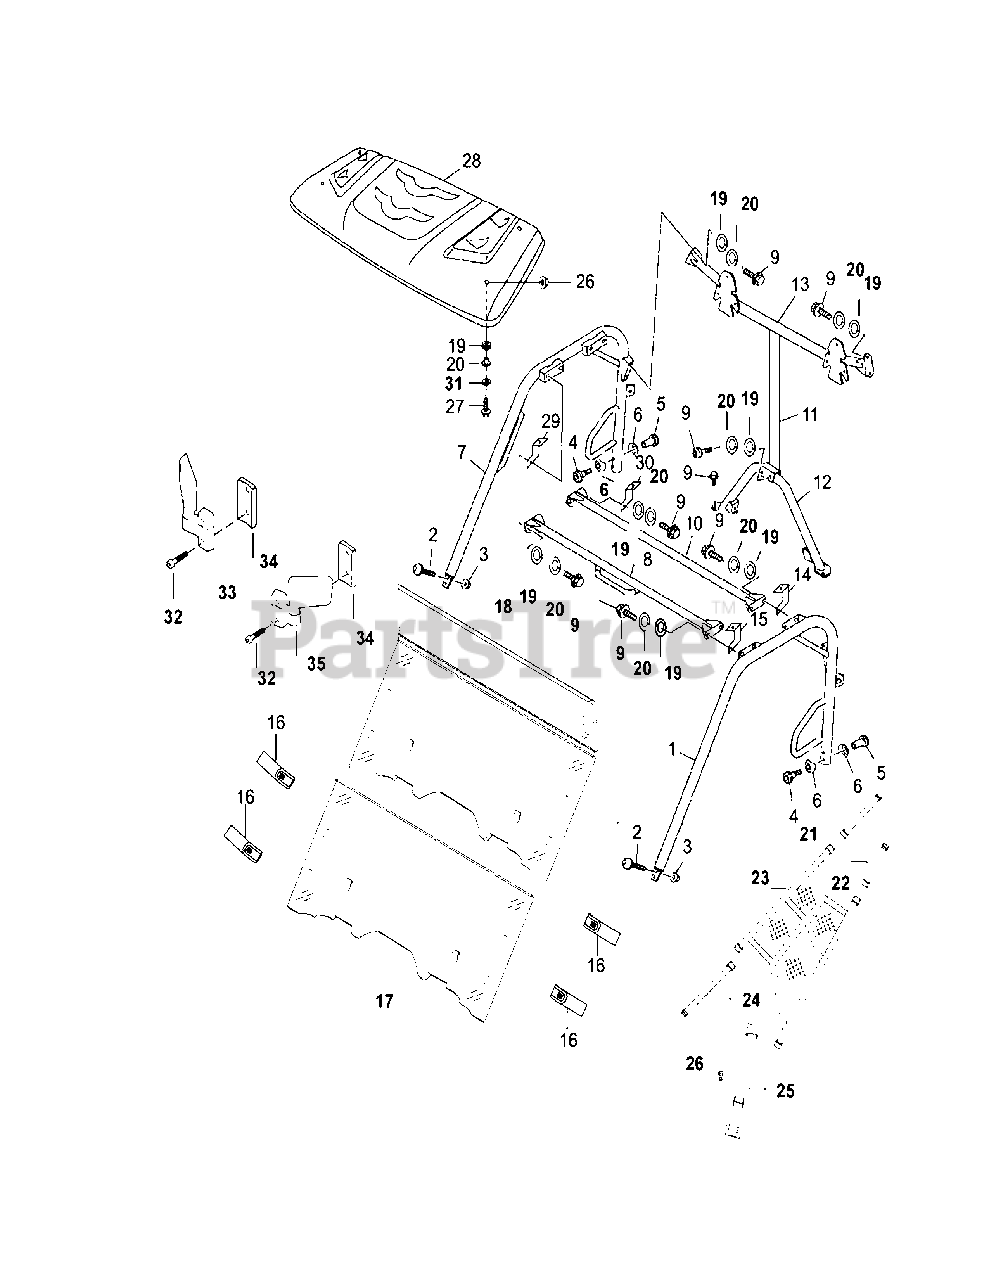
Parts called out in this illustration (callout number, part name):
1	Front Part of Roof Rod (Left)
2	Hexagon Socket Head Screw M10x1.25x45
3	Hexagon flange nut M10x1.25
4	Hexagon Socket Head Bolt M8x22-10x16
5	Hexagon Socket Head Bolt M8x25
6	Curved Washer
7	Front Part of Roof Rod (Right)
8	Horizontal Tube Assy I Shed
9	Hexagon flange bolt M10x1.25x20
10	Horizontal Tube Assy II Shed
11	Middle Rod Of Back Rest
12	Headrest Lower Support Bracket
13	Back Rest Support
14	Roof Rear Support (L)
15	Roof Front Support (L)
16	Clamp Assy
17	Front Windshield (Lower)
18	Front Windshield (Upper)
19	Spring washer -10
20	Washer10x20x2
21	Rubber Strip I
22	Rubber Latch II
23	Protective Net
24	Rubber Strip IV
25	Position Return Band III
26	Cross small plate head screw M5x16
27	Hexagon Flange Bolt M6x30
29	Roof Front Support (R)
30	Roof Rear Support (R)
31	Spring Washer -6
32	Hexagon Socket Head Screw M6x30
33	Right Mirror Assy
34	Mirror Mounting Bracket
35	Left Mirror Assy
